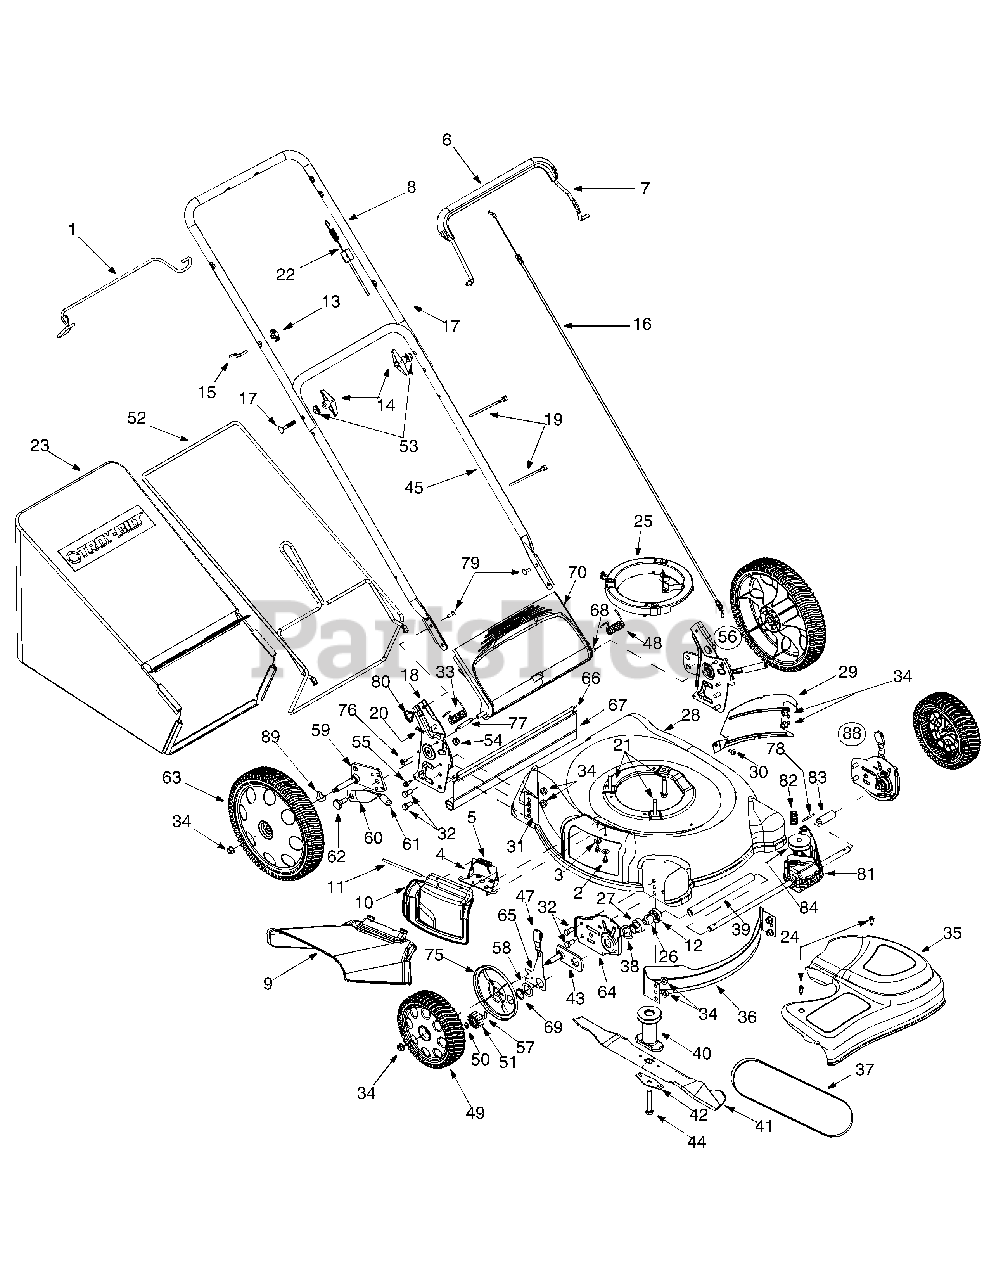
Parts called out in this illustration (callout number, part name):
1	Lower Bail Handle
2	TT Screw 1/4-20 x 0.5
3	Bell Washer .265 x 0.75
4	Deflector Chute Adapter
5	Torsion Spring
6	Deluxe Bail Cover
9	Chute Deflector
10	Mulch Plug Complete
11	Hinge Pin
12	Bearing Retainer
13	Handle Knob
14	Handle Knob
16	Control Cable - 40.75"
17	Carriage Bolt 5/16-18 x 2.0
18	RH Handle Bracket
18	LH Handle Bracket
19	Cable Tie
20	Cotter Pin
21	Self-Tapping Sems Screw
22	Drive Cable - 50.50"
23	Grassbag Assembly
24	Shoulder Screw # 12 -24
25	Engine Spacer
26	Bearing Sleeve
27	Bearing Support
28	21" Deck Service Kit
30	Screw AB: 1/4-14: .625
32	Hex Screw 3/8-16 x .75
33	Torsion Spring RH
34	Flange Lock Nut 3/8-16
35	Transmission Cover (Black)
38	Wave Washer
39	Sleeve Spacer 9.04" Lg.
40	Blade Adapter w/ Pulley
41	21" Mulching Blade
42	Blade Bell Support
43	Pivot Plate Assembly
44	Hex Screw 3/8-24 x 2.50
47	Adjustment Knob
48	Torsion Spring LH
49	Wheel 8 x 2.125
50	Snap Ring
51	Gear 14T RH FWD
53	Saddle Washer
54	Hex Flange Lock Nut 3/8-16
55	TT Scr. w/Washer 1/4-20 x .625
56	RH Handle Bracket Assembly
56	LH Handle Bracket Assembly
57	Dowel Pin
59	Pivot Arm Assembly - RH
59	Pivot Arm Assembly - LH
60	Rear Spring Lever
61	Foam Grip
62	Shoulder Scr .500 Dia. x .434
63	Wheel, 14 x 2.125
66	Wire
67	Rear Trailing Shield
68	Pivot Rod
69	Snap Ring
70	Rear Discharge Door
75	Wheel Dust Cap
76	TT Screw, 1/4-20 x .50
77	Spacer .375 x .50 x 1.02" Lg.
79	Carriage Bolt 1/4-20
80	Wing Nut
81	Transmission Assembly
82	Belt Tension Spring
83	Slev. Spacer 2.1" Lg.
84	Input Pulley
88	Height Adjustment Assembly RH
89	Spring Washer
